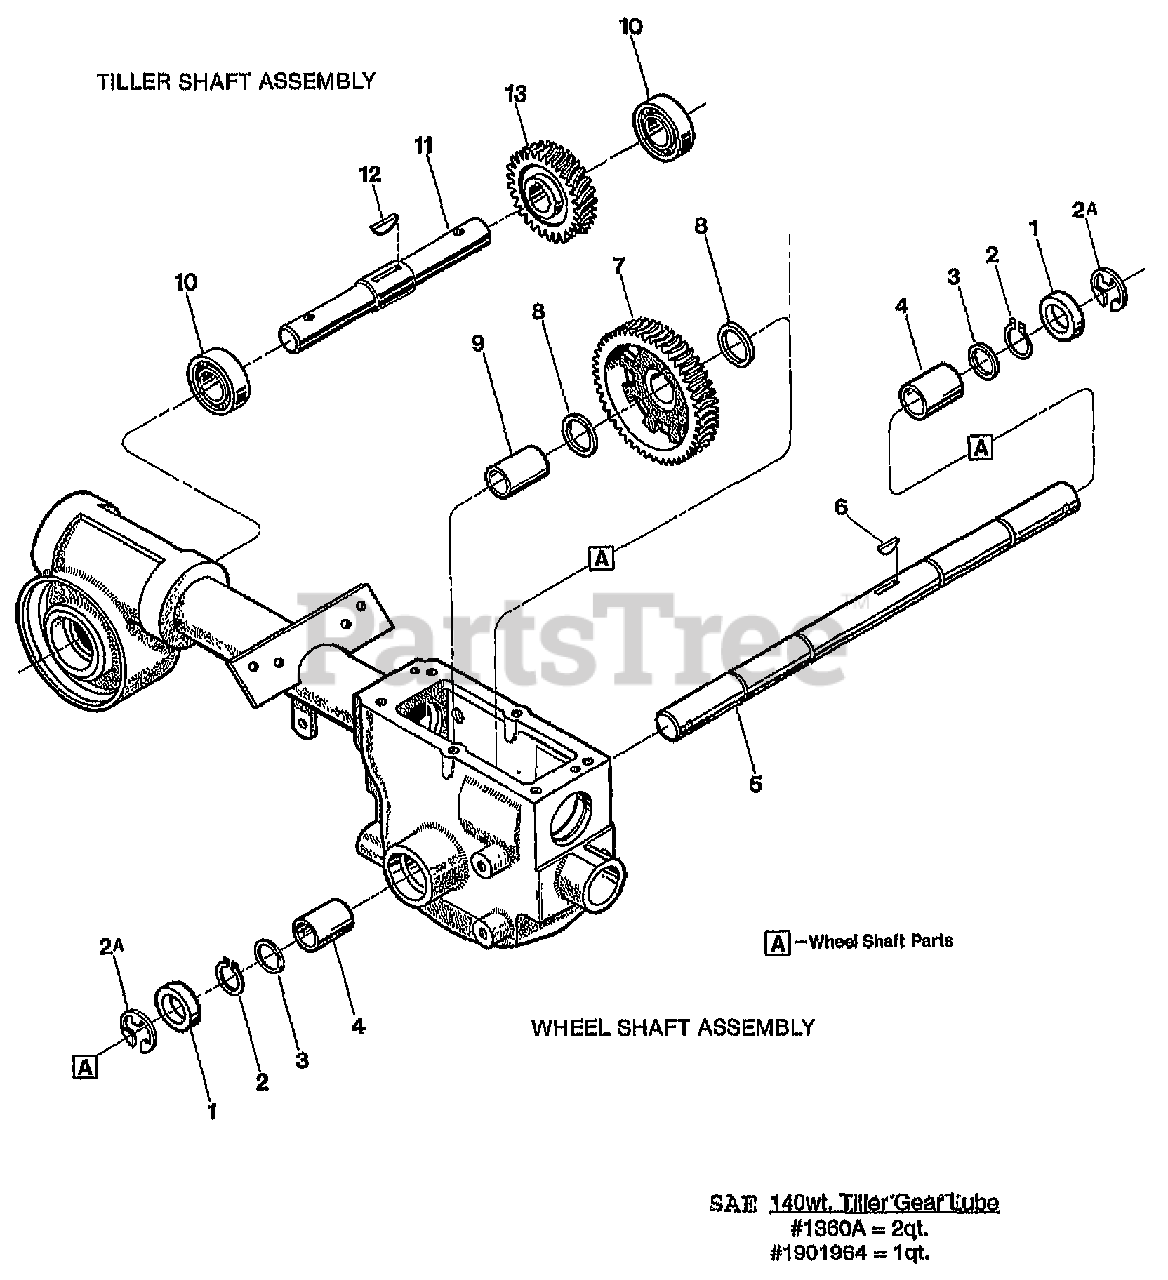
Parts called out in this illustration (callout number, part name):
1	SEAL-OIL WHEELSHAFT
2	RING-HEAVY EXT .906 ID
2A	RING-RETAINING 5133-989
3	SHIM-1.375X1.015X.062
3	SHIM-1.375X1.015X.03
3	SHIM-1.375X1.015X.015
3	SHIM-1.375X1.015X.01
4	BUSHING-1.25X1.005X1.5
5	ASSM-WHEELSHAFT W/KEY (AXLE)
6	KEY-HI PRO .25X.938
7	GEAR-MACH (WORM GEAR)
8	SHIM-1.234X1.015X.01
9	SPACER-WHEEL SHAFT
10	BEARING-BALL
11	SHAFT-W/KEY (TILLER) (INCL. 12)
12	KEY-WOODRUFF .25X1.12
13	GEAR-TILLER MACH
